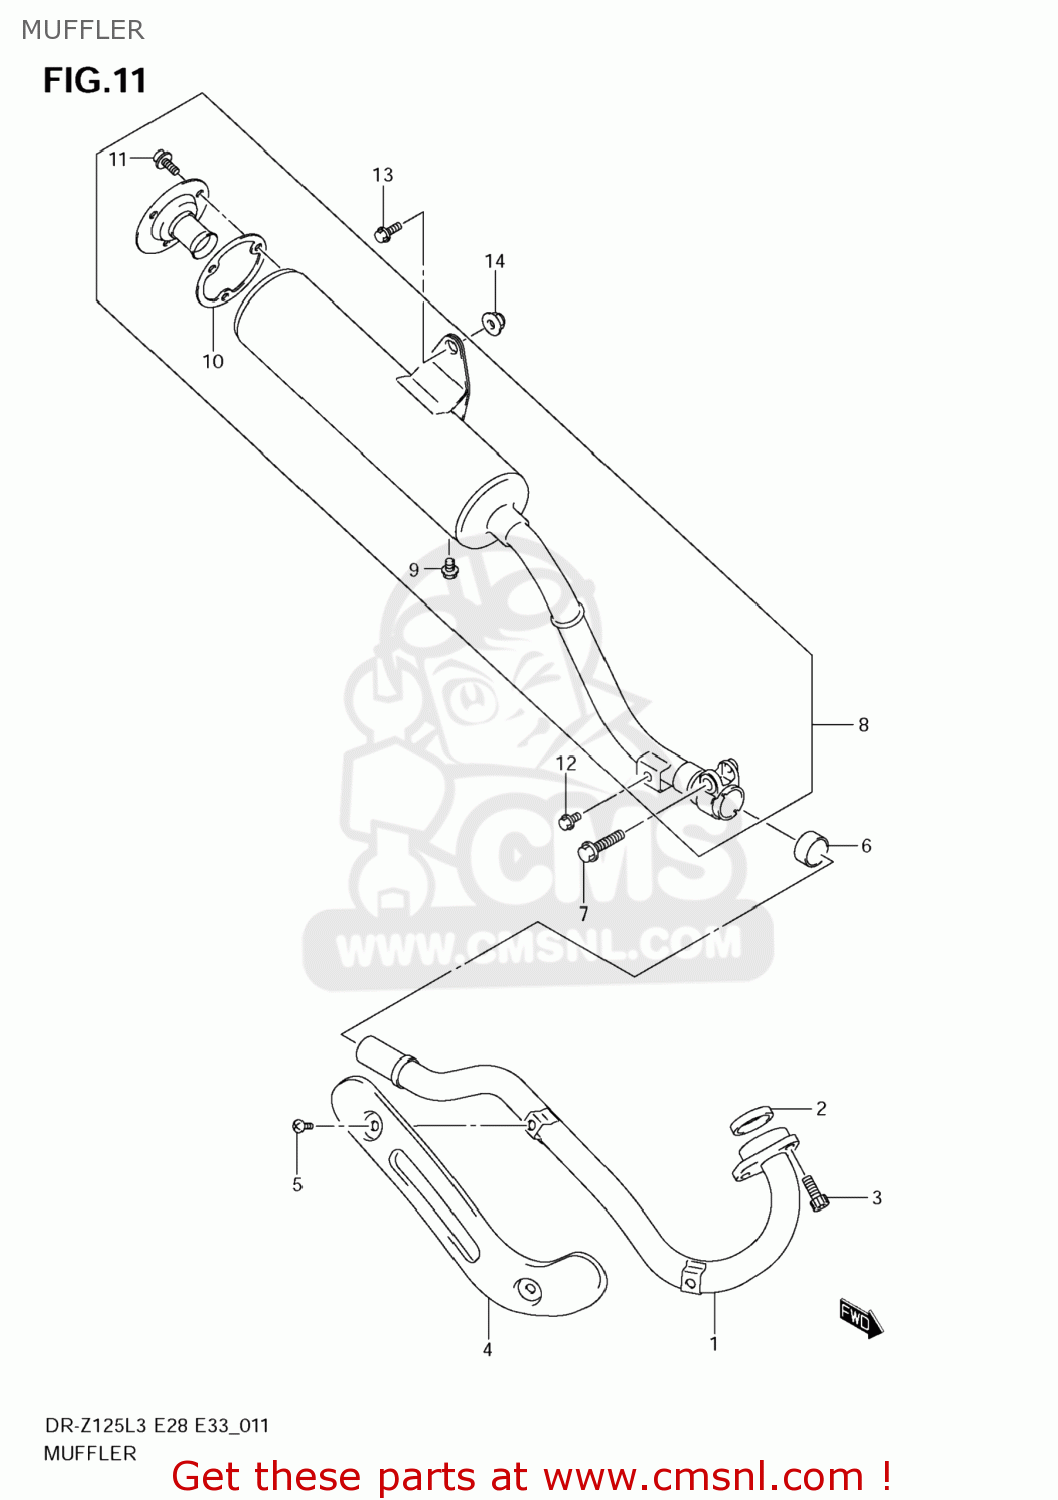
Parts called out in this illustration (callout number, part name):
1	PIPE,EXHAUST
2	GASKET (NAS)
3	BOLT
4	COVER,EXHAUST PIPE
5	SCREW(6X10)
6	CONNECTOR,MUFFLER
7	BOLT
8	BODY,MUFFLER
9	BOLT
10	GASKET,ARRESTER (NAS)
11	BOLT
12	BOLT
13	BOLT(8X23)
14	NUT
